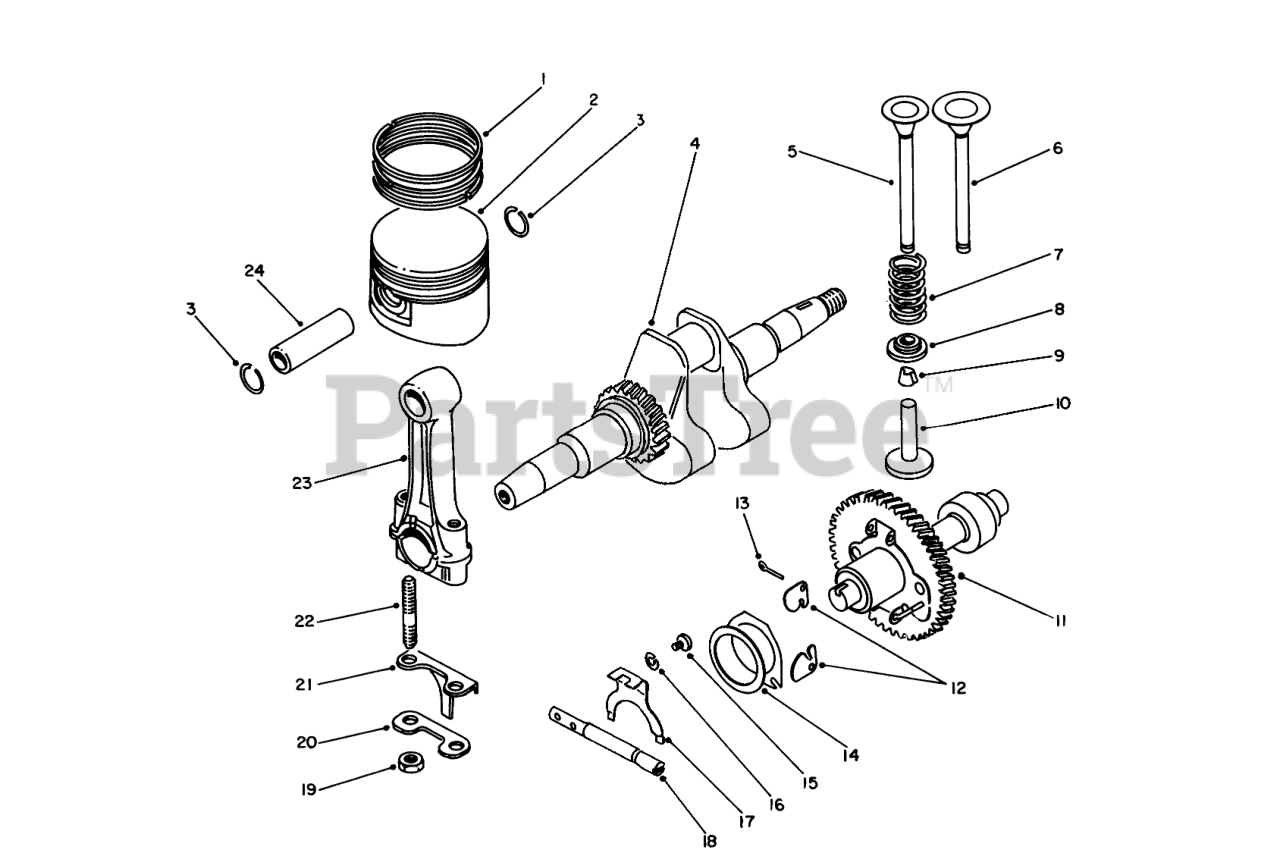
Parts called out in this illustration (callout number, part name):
1	Ring Set-Piston Std.
2	Piston Std
3	CIRCLIP
4	Crankshaft
5	EXHAUST VALVE
6	Valve-Intake
7	Spring-Valve
8	Retainer
9	Cotter
10	Tappet (L:40.26)
11	Cam Shaft
13	Cotter Pin
14	Spacer
15	SCREW
16	Washer
17	Plate-Shift
18	Shaft-Throttle Return
20	LOCK PLATE
21	Plate-Splash
22	Stud Bolt
23	Rod-Connecting (Incl. Ref. # 19-22)
24	PISTON PIN
